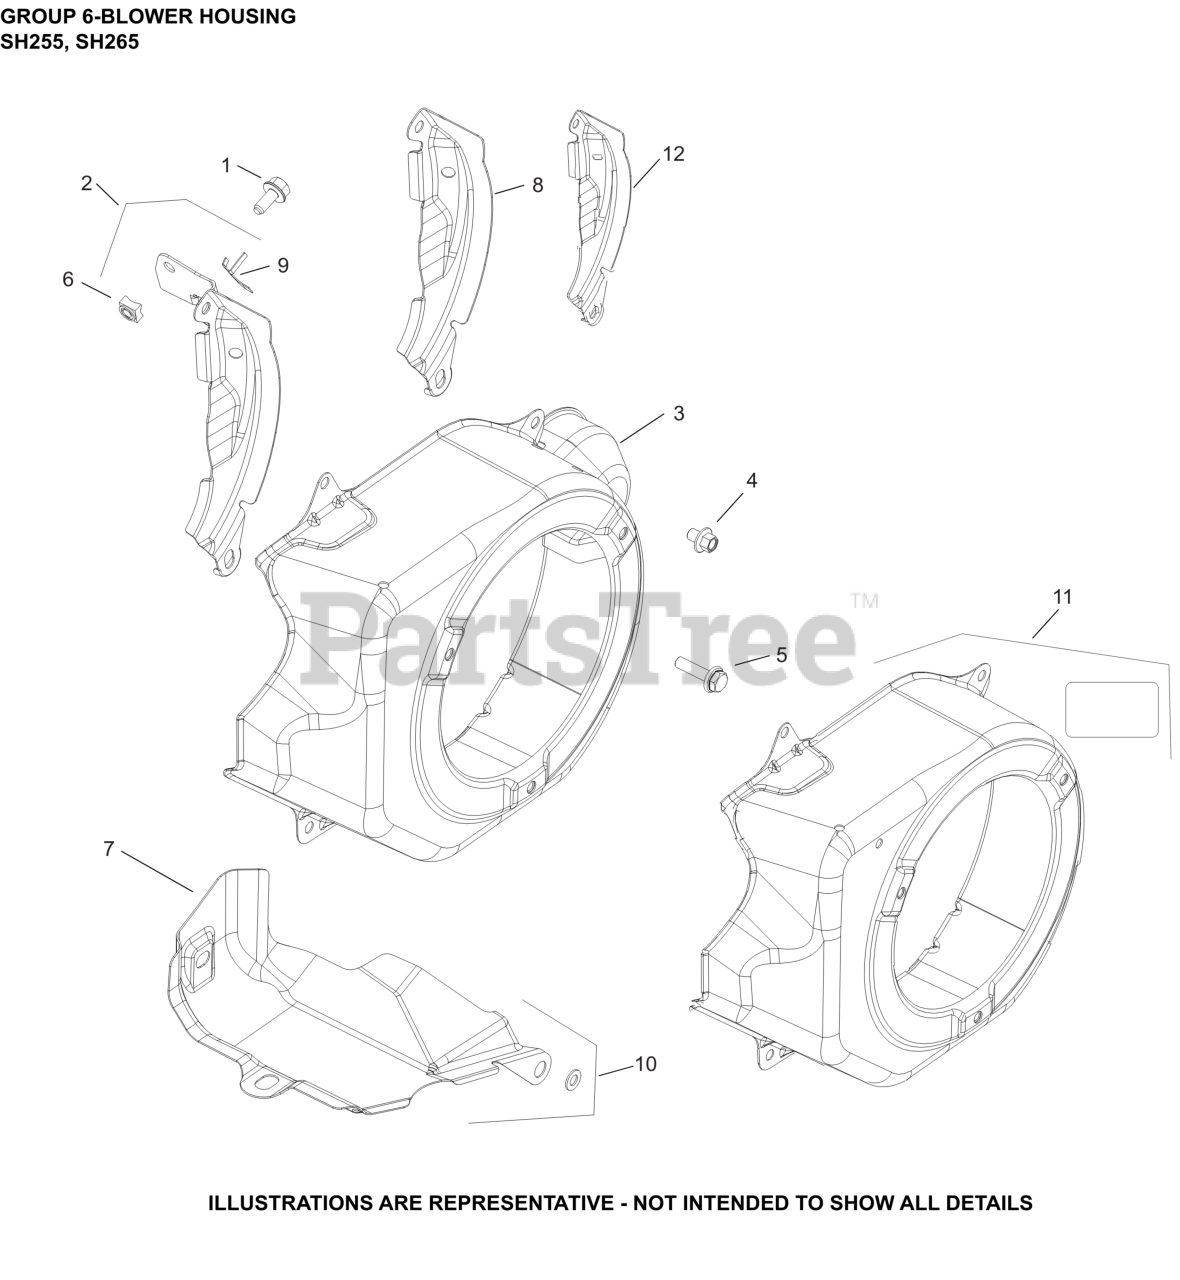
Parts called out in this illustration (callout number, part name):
1	SCREW, HEX FLANGE (M6)
2	COVER, HOUSING LOWER BLOWER ASSEM
3	HOUSING, BLOWER ASSEMBLY
4	SCREW, M6 X 8 HEX FLANGE HEAD
5	SCREW, M6 X 22
7	KIT, CYLINDER SHIELD
